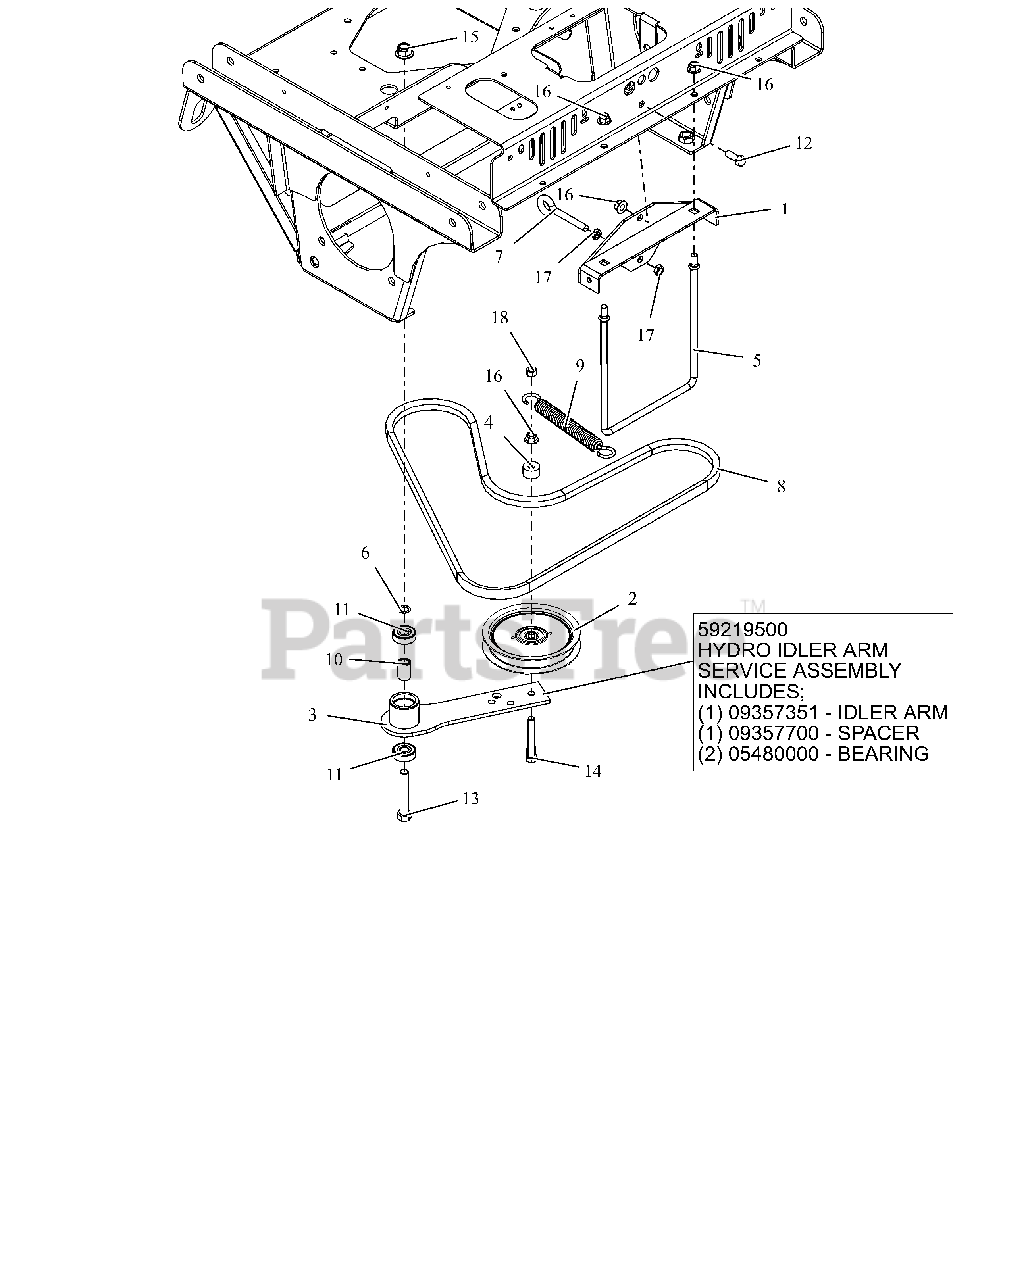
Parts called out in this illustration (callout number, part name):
1	SPRING ANCHOR BRKT WMT - BLACK
2	IDLER, FLAT-5.00X.75
3	HYDRO DRIVE IDLER ARM WMT- BLK
3	KIT, HYDRO IDLER ARM PT200/400
4	SPACER .390X1.000X.562
5	ROD, BRAKE MTG
6	WASHER, .500X.750X.020 THRUST
7	BLT-EYE .375-16X2.50 YWZC
8	V-BELT, COGGED B-RAW EDGE
9	SPRING, EXTENSION
10	SPACER .510 X .75 X 1.1485
11	BRG-BALL .500X1.38X.437
12	BLT,HEX .38-16X1.00 G5 ZCC
13	BLT, HEX .50-13X3.00 G5 ZCC
14	BLT, HEX .38-16X2.75 G5 ZCC
15	NUT,NYL-FLG .50-13 GF ZCC
16	NUT,NYL-FLG .38-16 GF ZCC
17	NUT-JAM .375-16 G2 ZCC
18	NUT-LK-CTR .38-16 ZC120
